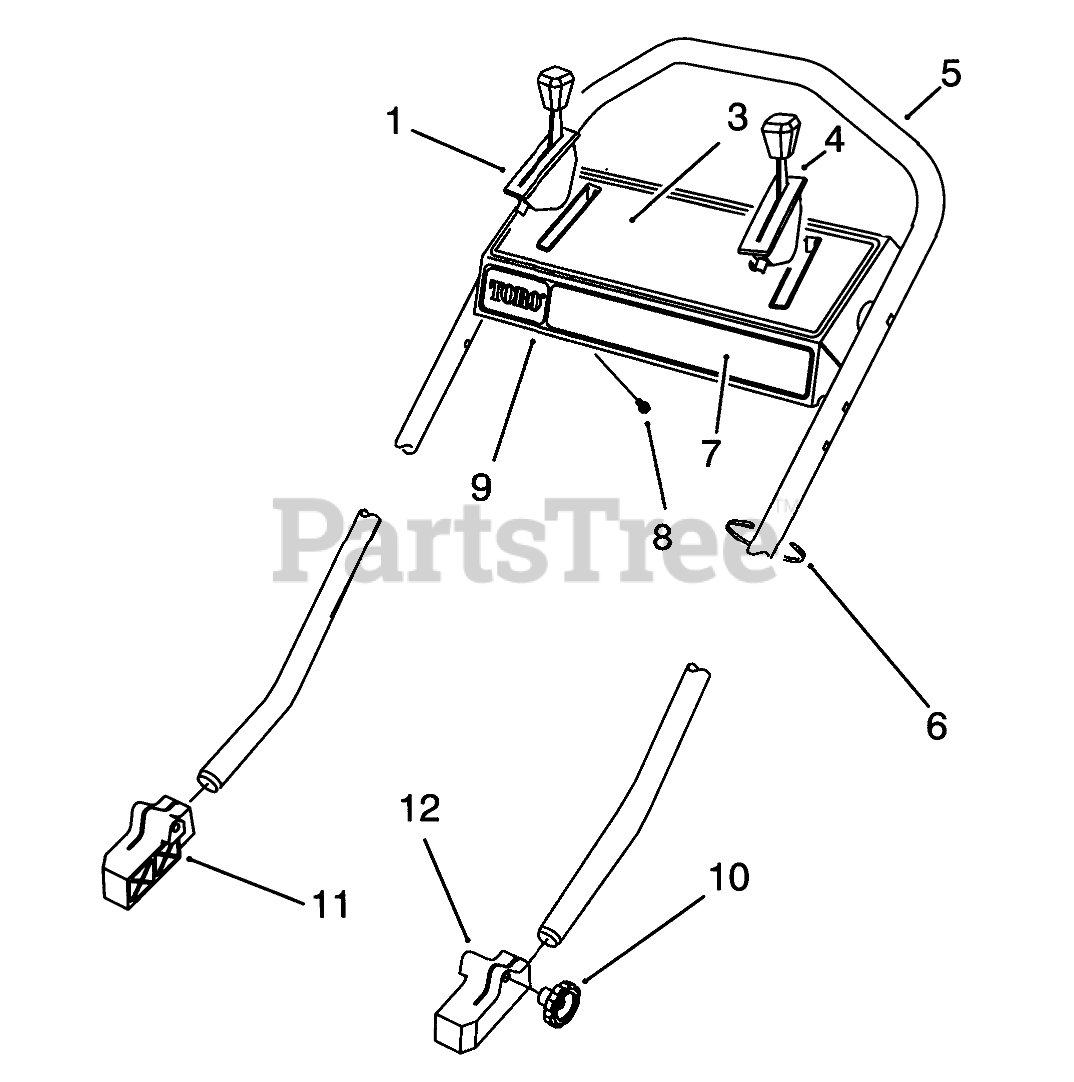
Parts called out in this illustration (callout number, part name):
1	GROUND SPEED CONTROL
3	DECAL-INSTRUCTION OHV
4	THROTTLE CONTROL
5	HANDLE PVC DIP
6	TIE-CABLE
7	DECAL - PANEL 2 CYCLE
8	SCREW-HWHTF
9	Control Panel Assembly (Incl. Ref. #2, 3, & 7)
11	MOUNT-HANDLE, RH
12	MOUNT-HANDLE, LH
